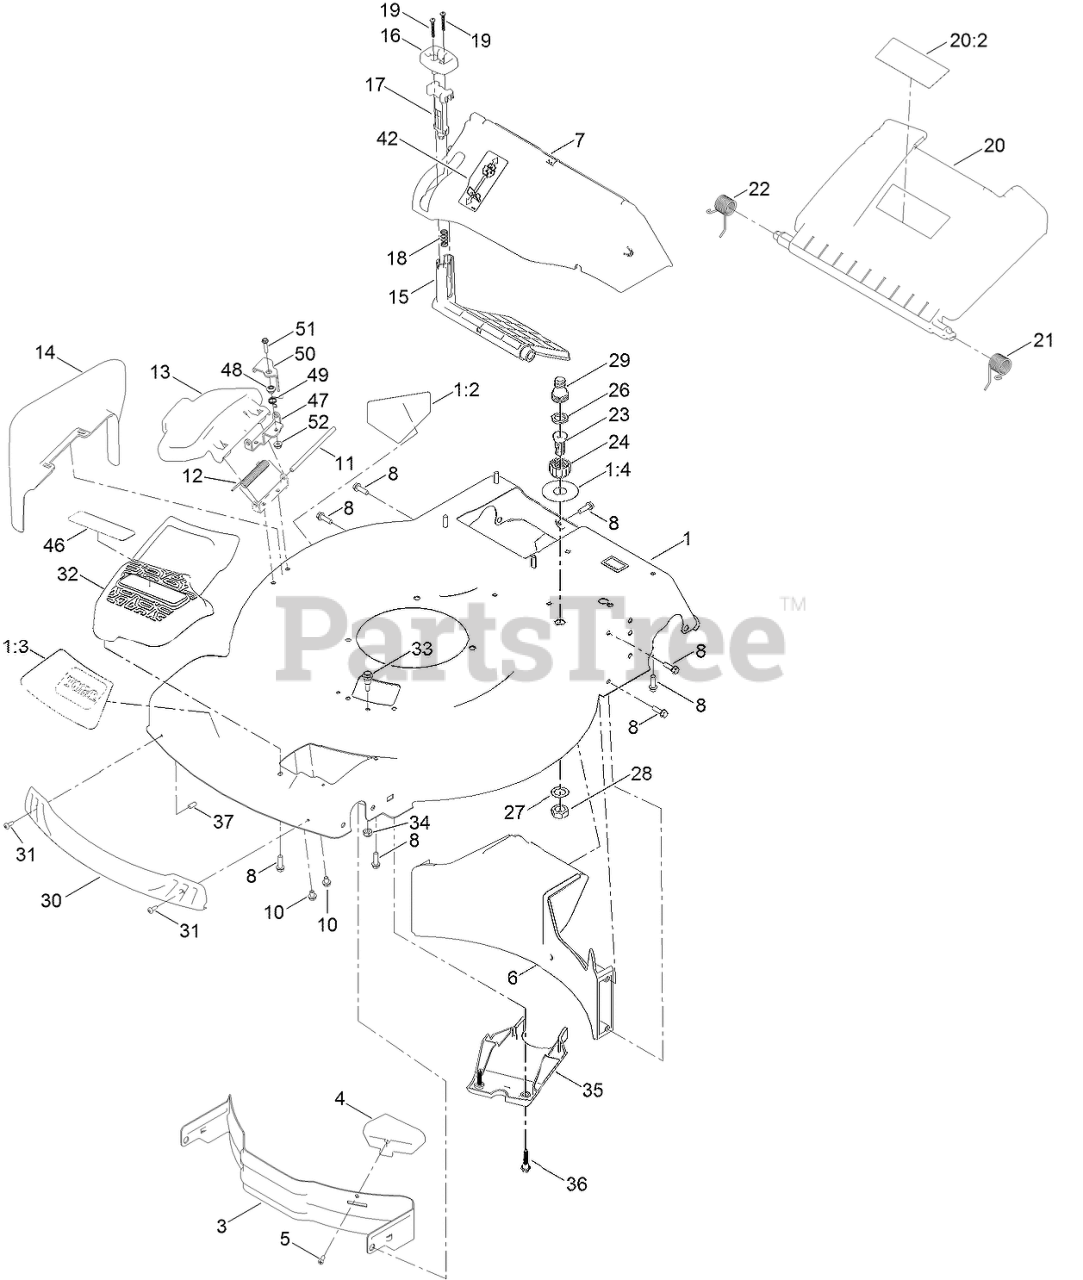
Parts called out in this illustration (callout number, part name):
1	HOUSING ASM
1:2	DECAL-DANGER
1:3	DECAL-DECK
1:4	DECAL-QUICK WASH
3	BAFFLE-FRONT
4	KICKER-FRONT
5	SCREW-PPH
6	BAFFLE-REAR
7	CHUTE-RECYCLE
8	SCREW-HWH
10	SCREW-HWH
11	ROD-COVER
12	SPRING-TORSION
13	DEFLECTOR-SIDE
14	CHUTE-DISCHARGE, SIDE
15	DEFLECTOR-RECYCLE
16	KNOB-RECYCLE
17	LATCH-RECYCLE
18	SPRING-COMPRESSION
19	SCREW-PPH
20	REAR DOOR ASM
20:2	DECAL-WARNING
21	SPRING-TORSION
22	SPRING-TORSION
23	PORT-WASHOUT
24	COUPLING-HOSE, WASHOUT PORT
26	WASHER-SEAL, WASHOUT PORT
27	WASHER-TOOTH, INTERNAL
28	NUT-JAM
29	ADAPTER-CONNECT, QUICK
30	BUMPER
31	SCREW-FORMING, THREAD
32	COVER-BELT, FRONT
33	BOLT-SHOULDER
34	NUT-LOCK, NI
35	COVER-BELT, FRONT
36	SCREW-SHOULDER, HHF
37	CAP-PLUG
46	DECAL-BELT COVER, POWEREVERSE
47	BRACKET-LOCKOUT
48	SPACER
49	SPRING-TORSION
50	LEVER-LOCKOUT
51	SCREW-HWH
52	NUT-LOCK, FLANGE
